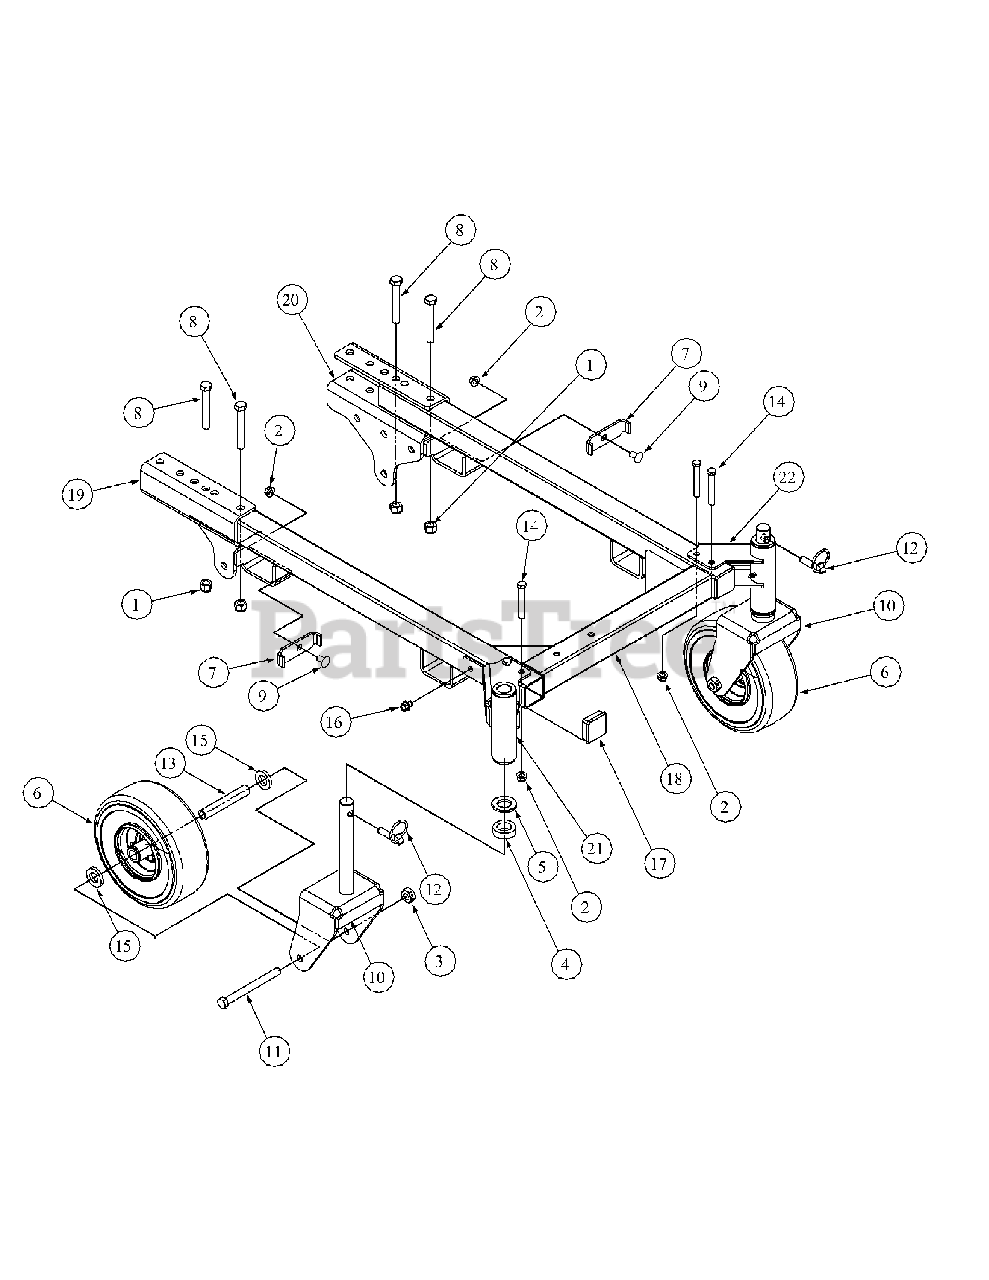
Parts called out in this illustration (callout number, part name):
1	Lock Nut, Nylon Insert, 1/2-13
2	Flange Lock Hex Nut, 3/8-16
3	Center Lock Nut, 1/2-20
4	Spacer, 1.015 ID x 1.62 OD x .5
5	Special Washer
6	Wheel Assembly, 9.0 x 3.50-4
7	Wear Plate
8	Capscrew, 1/2-13 x 3.5
9	Carriage Bolt, 3/8-16 x .75 Lg
10	Caster Assembly
11	Hex Cap Screw, 1/2-20 x 5.50
12	Klik Pin, 1.75 Lg
13	Wheel Spacer
14	Hex Cap Screw, 3/8-16, 2.75
15	Spacer, .812 ID x .268 Lg
16	Hex Index Washer Screw, 3/8-16, .5
17	Square Tube Plug Fitting
18	Fabricated Deck Frame Assembly
19	Right Hand Frame Bracket Support
20	Left Hand Frame Bracket Support
21	RH Caster Mount Bracket Assembly
22	LH Caster Mount Bracket Assembly
